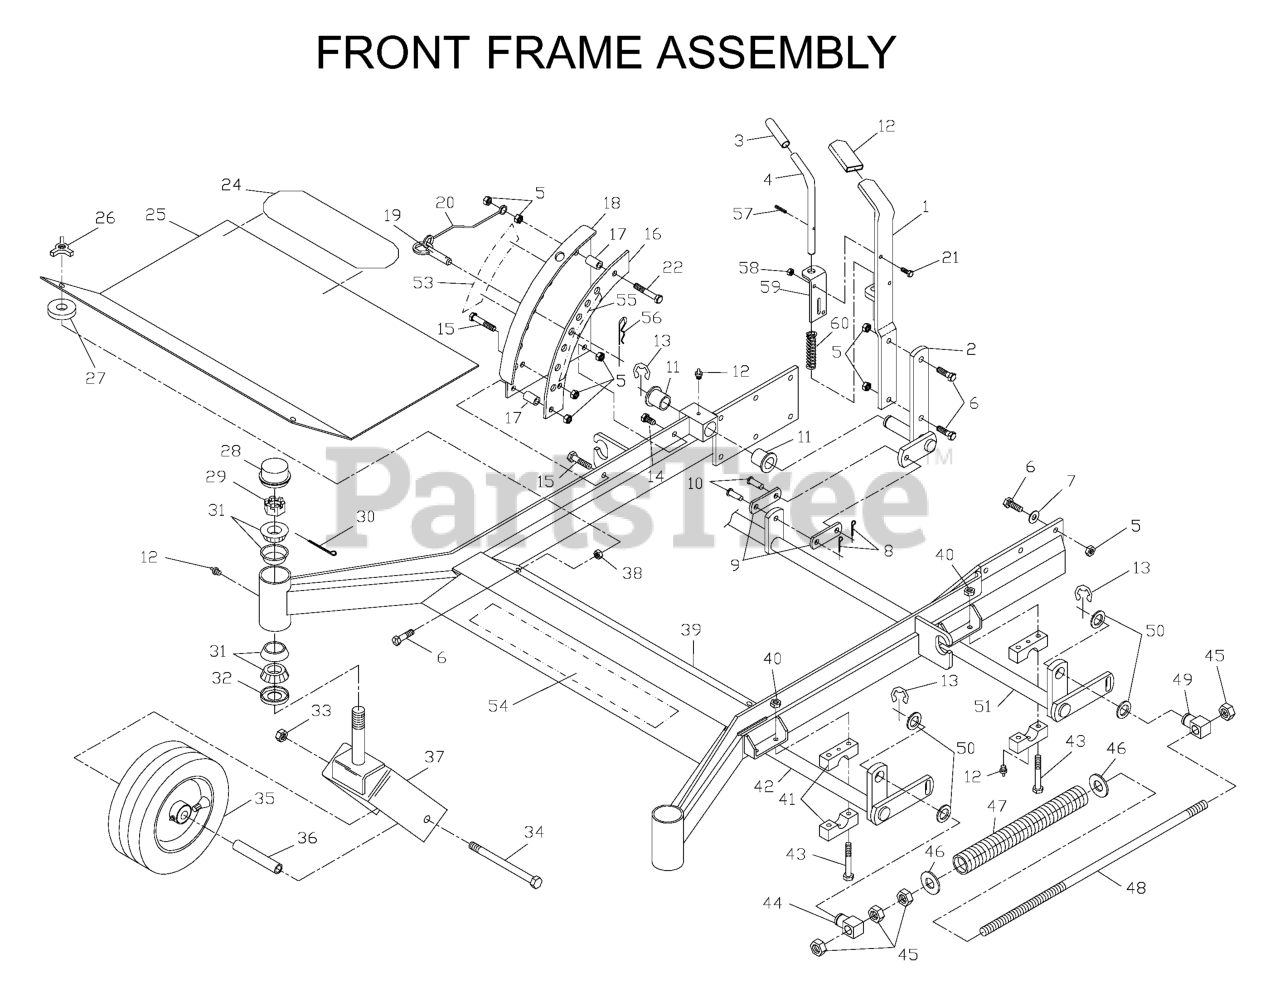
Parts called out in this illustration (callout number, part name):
1	LIFT LEVER
2	DECK LIFT ARM
5	NUT 3/8C CENTERBLOCK
6	HEX SCREW 3/8 X 1.25
7	WASHER, 3/8 DISC SPRING SPEC
8	RP_COTTER PIN 1/8 X 3/4
10	CLEVIS PIN 3/8 X 1 1/8
11	BUSHING, FLANGED
13	E-RING 7/8
14	SCREW 3/8C X 3/4 HEX CAP
15	HCS 3/8C X 2
16	ARC-DECK LIFT
18	PLATE WELDMENT
21	HCS 1/4C X 3/4 HCS
22	HCS 3/8C X 2 1/4
24	ANTI-SKID PAD
25	FOOT PLATE
26	KNOB, THREE PRONG
27	WASHER, RUBBER
28	GREASE CAP
29	NUT 1"C HEX SLOTTED
30	COTTER PIN 1/8 X 2
31	BEARING W/CUP
33	NUT 1/2-13 HEX NYLOC ZD
34	SCREW 1/2C X 7 1/2 HEX CAP
35	TIRE.ASSEM.13X5-6.SMOOTH.SILVE
36	SPACER, CASTER
37	CASTER YOKE ORANGE
38	NUT 3/8C WHIZ
39	FRONT FRAME WELDMENT
40	NUT 5/16C CENTERLOCK
41	LIFT BLOCK
42	FRONT LIFT ROD
43	BOLT 5/16C X 2 1/2
44	DECK MOUNT SWIVEL
45	NUT 5/8C HEX
46	WASHER, 5/8 FLAT
47	DECK SUPPORT SPRING
48	DECK LIFT ROD
49	DECK MOUNT SWIVEL, THREADED
50	BSHG .875 X 1.375 X .074 ZD
53	DECAL, DECK HEIGHT
54	DECAL, HUSQVARNA 17.5"
55	DECAL, HEIGHT
56	HAIRPIN #4
57	ROLL PIN 3/16 X 1-1/4 ZD
58	NUT 1/4C CENTERLOCK
59	PIN MT, UPPER
539102485	ROLLER BEARING
539102546	TIRE - FRONT
539104573	RIM
539902484	FLANGED BEARING
539912234	VALVE STEM TR-412
539976997	ZERK 1/8 NPT
